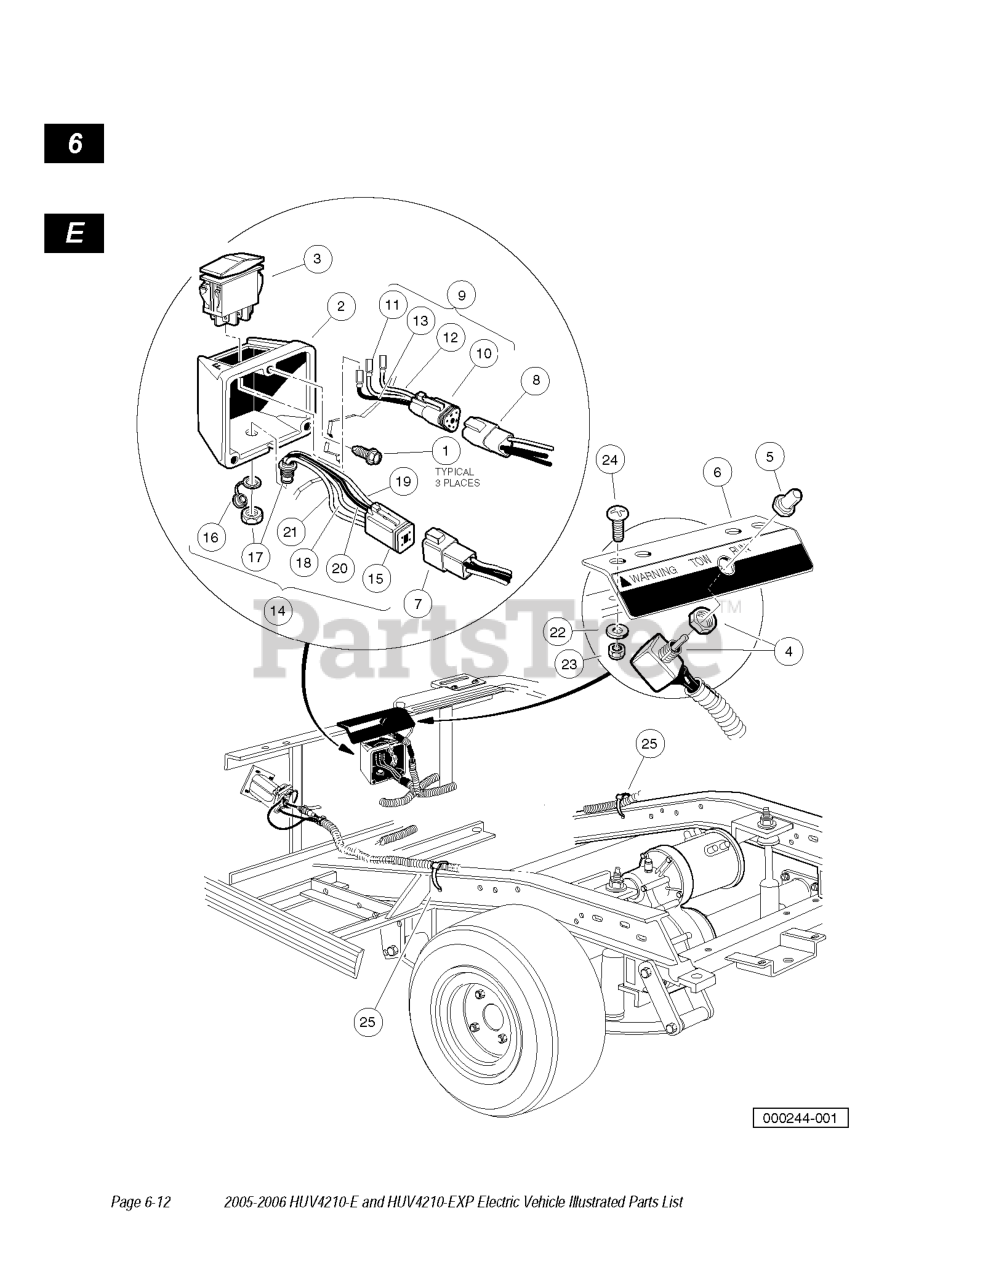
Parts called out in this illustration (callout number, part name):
1	SCREW HX TYP TT
2	CASE, F&R SWITCH, IQ SYSTEM
3	SWITCH ROCKER - SINGLE POLE
4	SWITCH ASSY, TOW
5	BOOT, SWITCH
6	BRACKET, TOW SWITCH MOUNTING
7	KIT, 4-PIN RECEPT & WEDGE LOCK
8	KIT 3PIN RECEPT AND WEDGE LOCK
9	WIRE ASM F&R SWITCH
10	KIT, 3 PIN PLUG & WEDGE LOCK
14	WIRE ASM IQDM PORT
15	KIT 4-PIN PLUG AND WEDGE LOCK
22	WASHER 1/4 FLAT
23	LOCKNUT, 1/4-20 NYLON INSERT
24	SCREW 1/4-20 X .75
25	TIE WRAP, 8" NYLON
